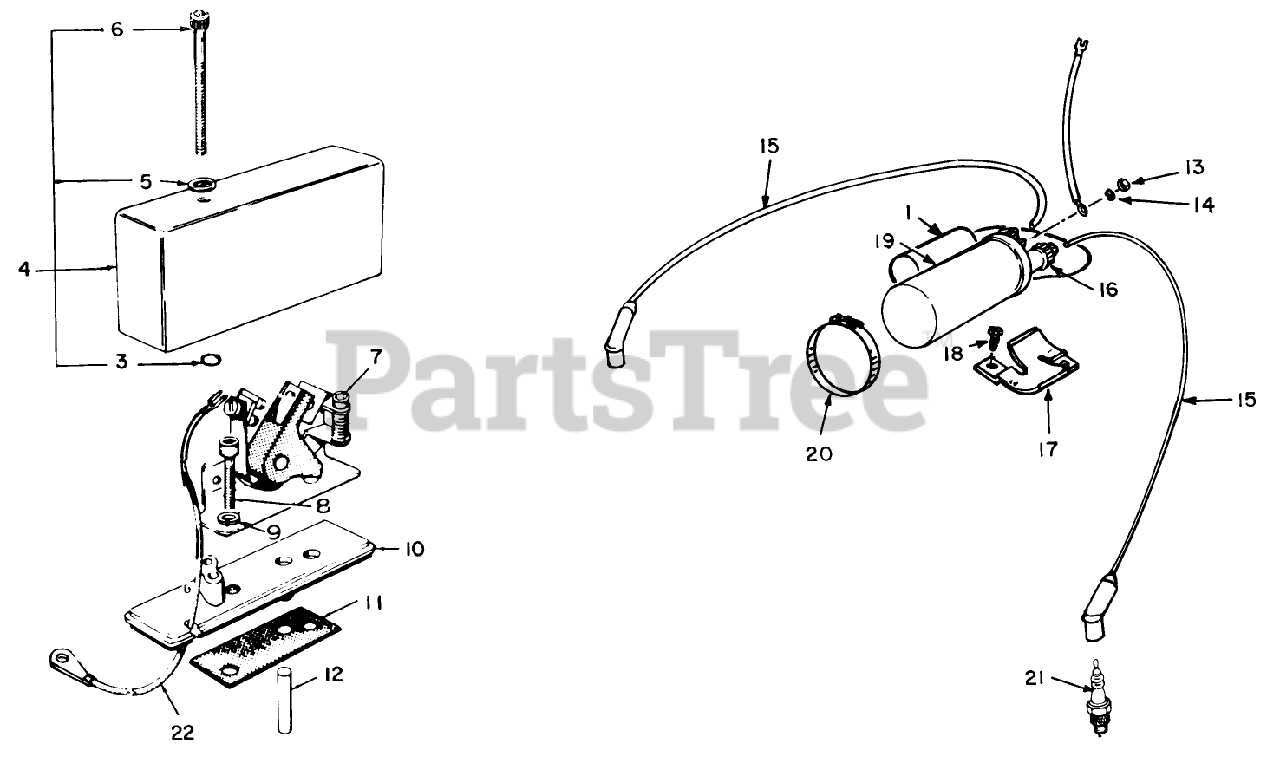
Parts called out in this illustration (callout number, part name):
1	CONDENSER
6	SCREW-HSH
9	SCREW-HH
11	GASKET
15	CABLE KIT
21	SPARK PLUG
